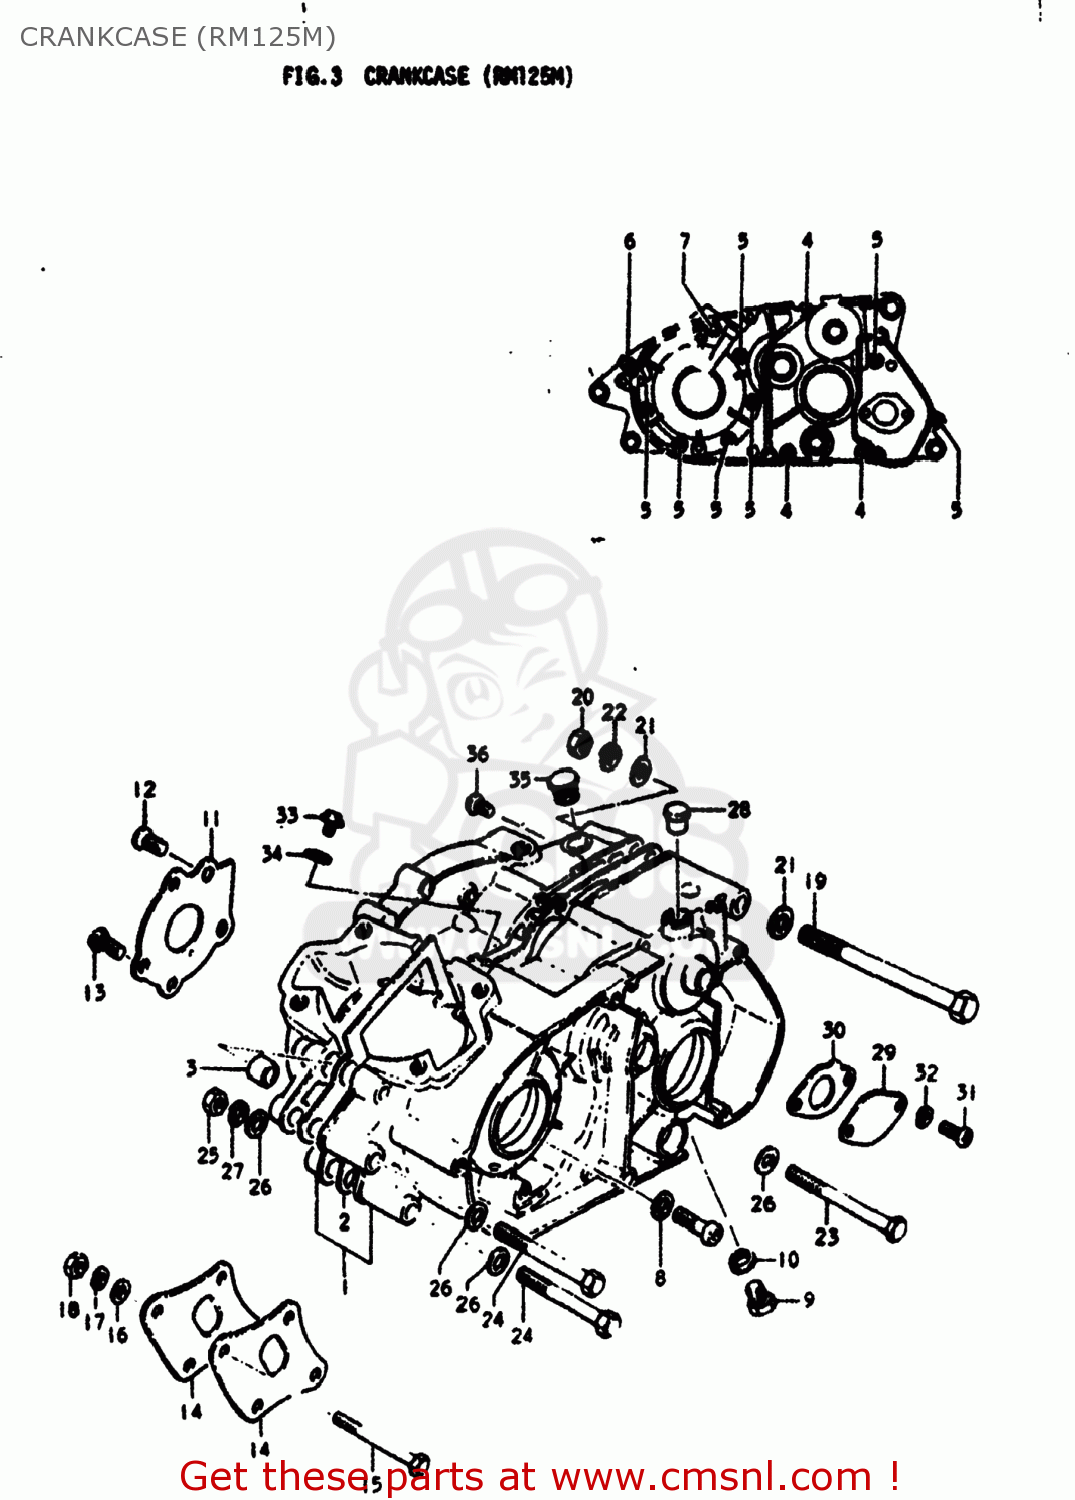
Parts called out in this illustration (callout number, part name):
1	CRANKCASE SET
2	GASKET,CRANKCASE (MCA)
3	PIN
4	SCREW
5	SCREW (6X45)
6	SCREW 6X80
7	SCREW 6X60
8	WASHER 6MM
9	PLUG
10	GASKET(10X14X3.6) (NAS)
11	PLATE,OIL RESERVOIR
12	SCREW
13	SCREW
14	PLATE,ENGINE MOUNTING
15	BOLT
16	WASHER
17	LOCK WASHER
18	NUT
19	BOLT
20	NUT
21	WASHER
22	LOCK WASHER
23	HEXAGON BOLT 8X80
24	BOLT
25	NUT
26	WASHER
27	LOCK WASHER
28	CAP(OD:14)
29	CAP,OIL PUMP DRIVE SHAFT
30	GASKET,OIL PUMP (MCA)
31	Screw
32	LOCK WASHER
33	BOLT
34	GASKET(6.2X11X1).2 (NAS)
35	Plug
36	SCREW,6X6
